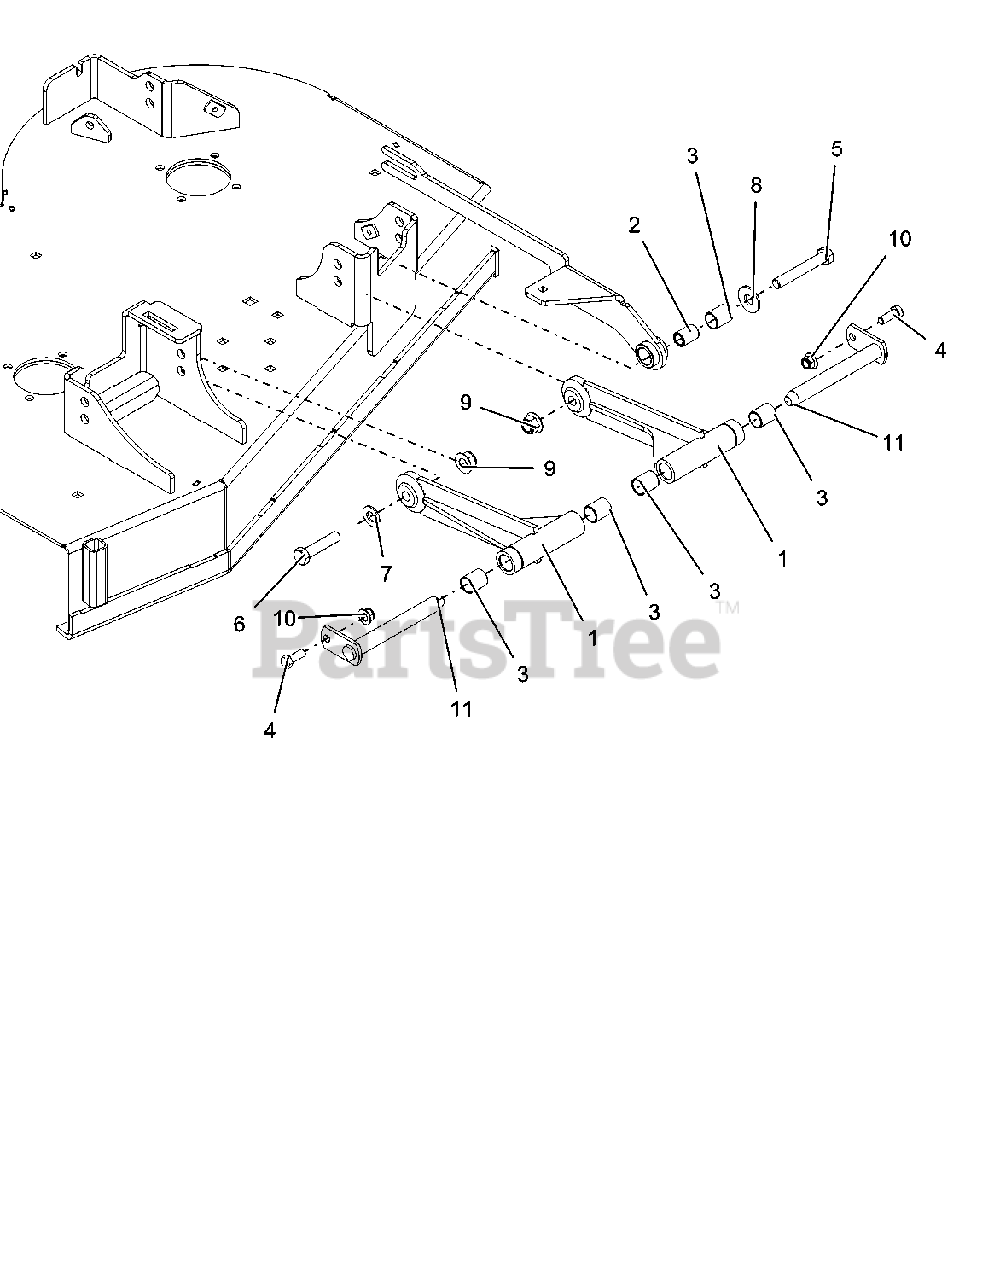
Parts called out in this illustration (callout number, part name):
1	WMT, DRAG LINK
2	BSHG, .515ID X .75ODX 1.080
3	BRG, .750 X .875 X 1.000
4	@BLT-HEX .38-16X1.00 GR5 YWZC
5	@BLT-HEX .50-13X3.25 GR5 YWZC
6	@BLT-HEX .50-13X2.25 GR5 YWZC
7	@WSHR-FL-STL.531X1.06X.095YWZC
8	@WSHR-FL-STL.563X1.38X.109YWZC
9	@NUT-LK-NYL-FLG .50-13 YWZC
10	@NUT-LK-NYL-FLG .38-16 YWZC
11	WELDMENT, MOWER MTG. PIN
